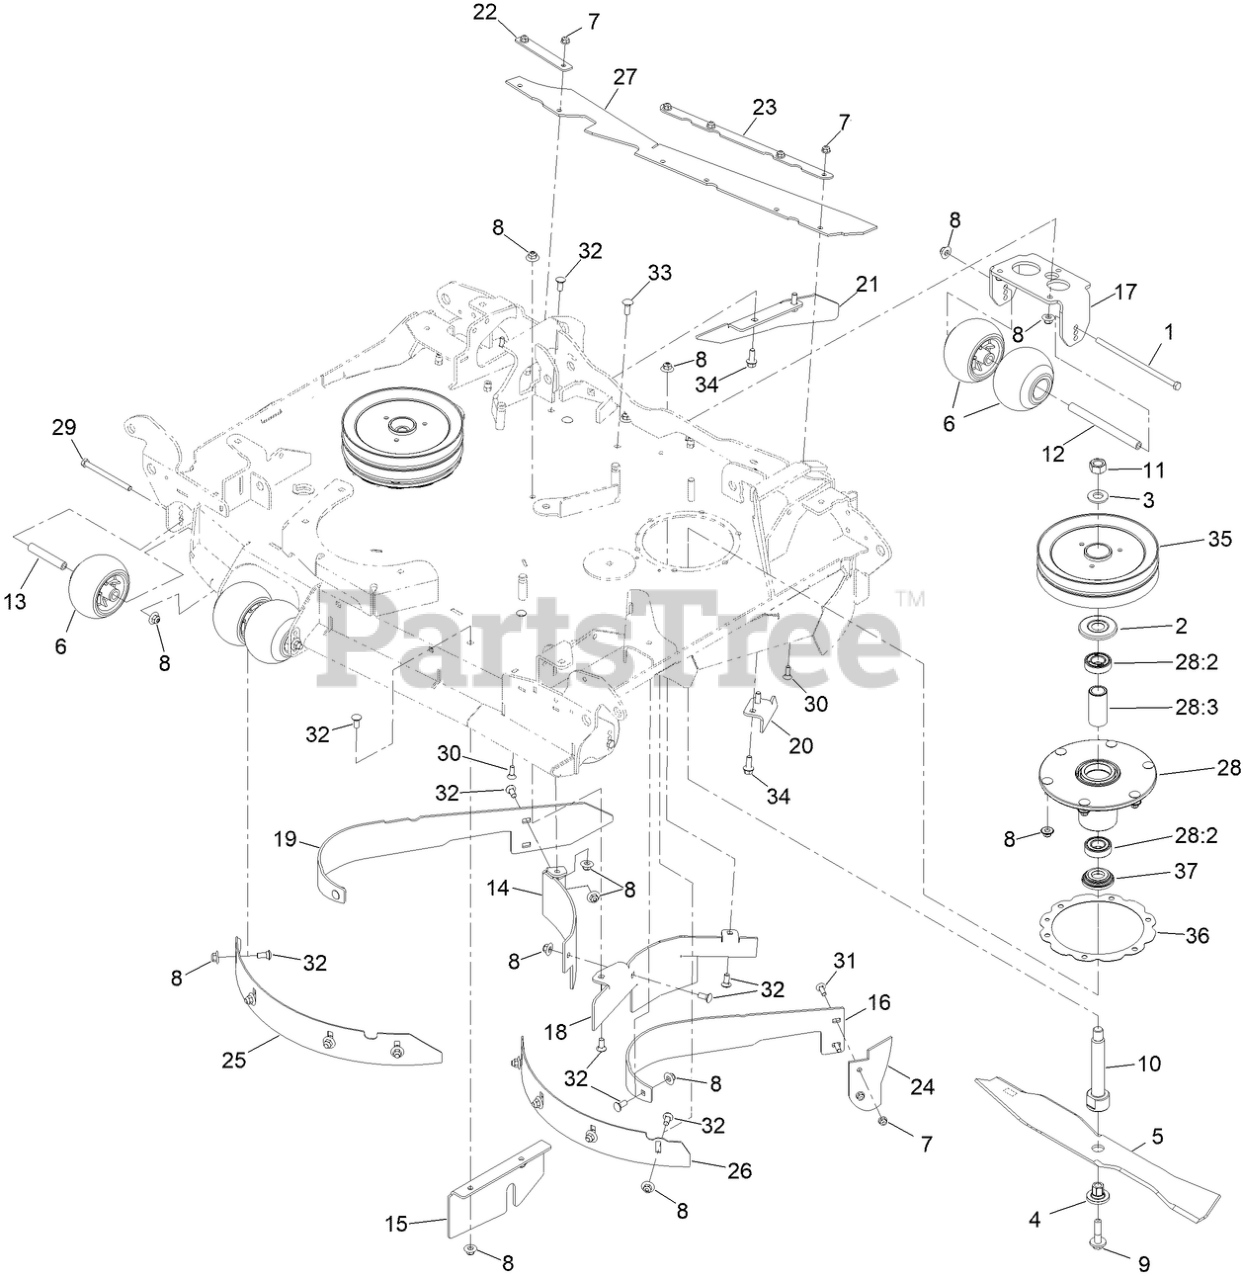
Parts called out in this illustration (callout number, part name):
1	SCREW-HH
2	GUARD-BEARING, TOP
3	WASHER
4	BUSHING-HEX
5	BLADE-24.50 MULCH
6	ROLLER-SCALP, ANTI
7	NUT-HF, NI
8	NUT-FLANGE, NI
9	SCREW-SEMS
10	SHAFT-SPINDLE
11	NUT-HEX
12	SPACER-WHEEL
13	SPACER-WHEEL SHORT
14	BAFFLE-CENTER, REAR (RH)
15	PLATE-BLOCK, FRONT
16	BAFFLE-DOGLEG, CENTER (LH)
17	BRACKET-ANTISCALP, REAR
18	BAFFLE-CENTER
19	BAFFLE-DOGLEG, CENTER (RH)
20	BAFFLE-BREAKER
21	PLATE-FIN, DISCHARGE
22	SUPPORT-FLAP, LH
23	SUPPORT-FLAP, LH
24	GUARD-DISCHARGE
25	BAFFLE-DEPTH, LH
26	BAFFLE-DEPTH, RH
27	FLAP-DISCHARGE
28	SPINDLE ASM
28:2	BEARING-BALL
28:3	SPACER-BEARING
29	SCREW-HH
30	SCREW-CARR
31	SCREW-CARR
32	BOLT-CARR
33	BOLT-CARR
34	SCREW-HHF
35	SHEAVE-DOUBLE BLADE DRIVE
36	RING-SPACER, HOUSING
37	GUARD-BOTTOM
